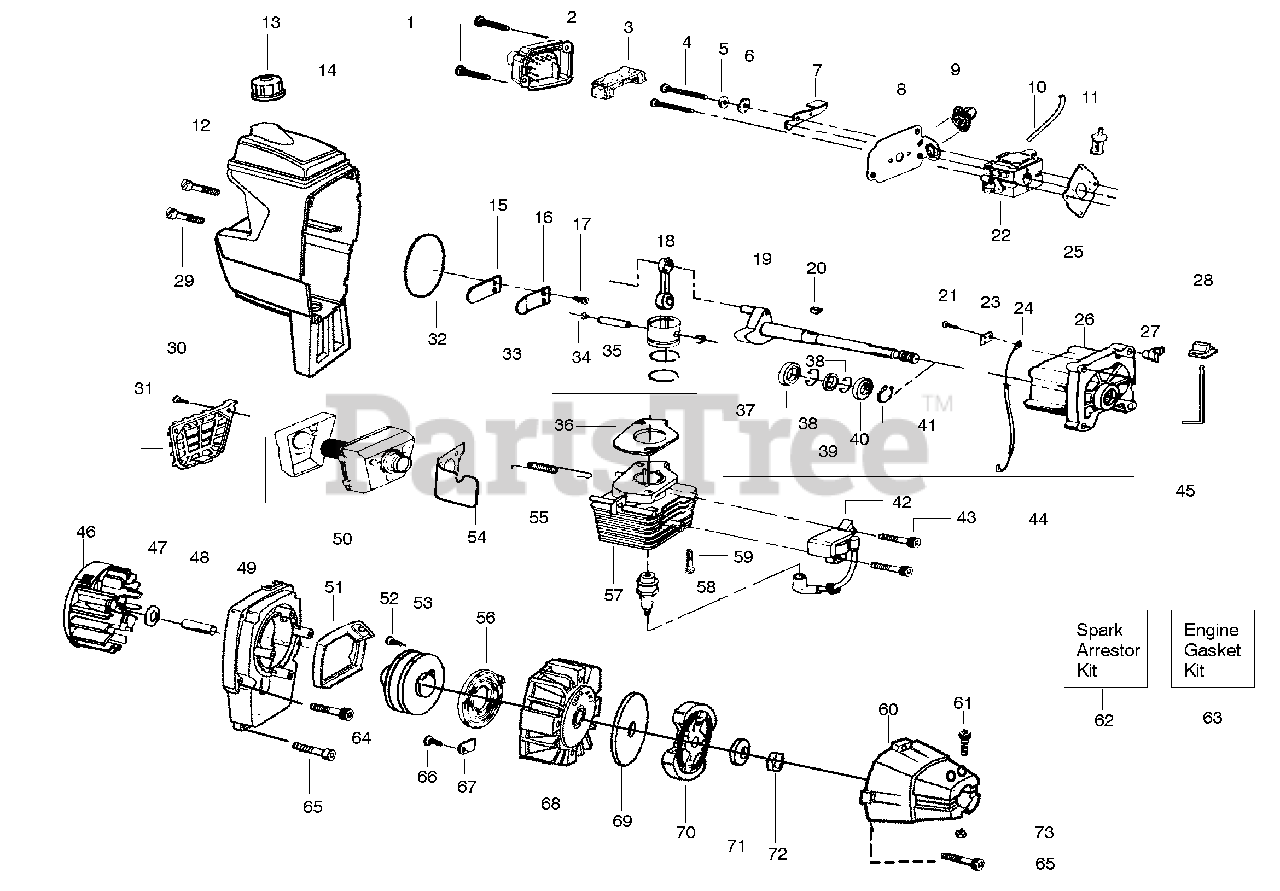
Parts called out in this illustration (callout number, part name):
2	Cover-Air Filter
3	Foam-Air Filter
7	Shutter-Choke
10	Kit-Fuel Line
11	Assy-Fuel Pick-up
13	Assy-Fuel Cap.
14	Assy-Shroud/Tank
16	Stop-Reed Valve
18	Assy-Connecting Rod
19	Assy-Crankshaft
22	Kit-Carburetor Ass'y. (WT-583)
22	Kit-Carburetor Ass'y. (WT-629)
23	Insulator-Switch
24	Assy-Leadwire
25	Gasket-Carb.(kit)
26	Assy-Crankcase.
31	Guard-Muffler
32	O-ring-C'case(kit)
34	Piston Pin Retainer
35	Piston Ring (2)
36	Gasket-Cyl. (kit)
37	Bearing-Inner
38	Ring-Retaining
39	Seal-Crankshaft
40	Bearing-Outer
41	Retaining Ring-C'shaft
42	Module-Ignition
44	Assy-C'case/C'shaft
45	Spring-Switch
46	Assy-Flywheel
48	Spacer-Clutch
51	Assy-Retainer/Eyelet
53	Kit-Starter Pulley
54	Heat Shield/Air Dam
55	Spring-Muffler
56	Spring-Starter
58	Spark Plug (RCJ-6Y)
60	Assy-Clutch Housing
62	Kit-Spark Arrestor
63	Kit-Engine Gasket
65	Screw
68	Assy-Pulley Housing
69	Washer-Clutch
70	Kit-Clutch Ass'y.
